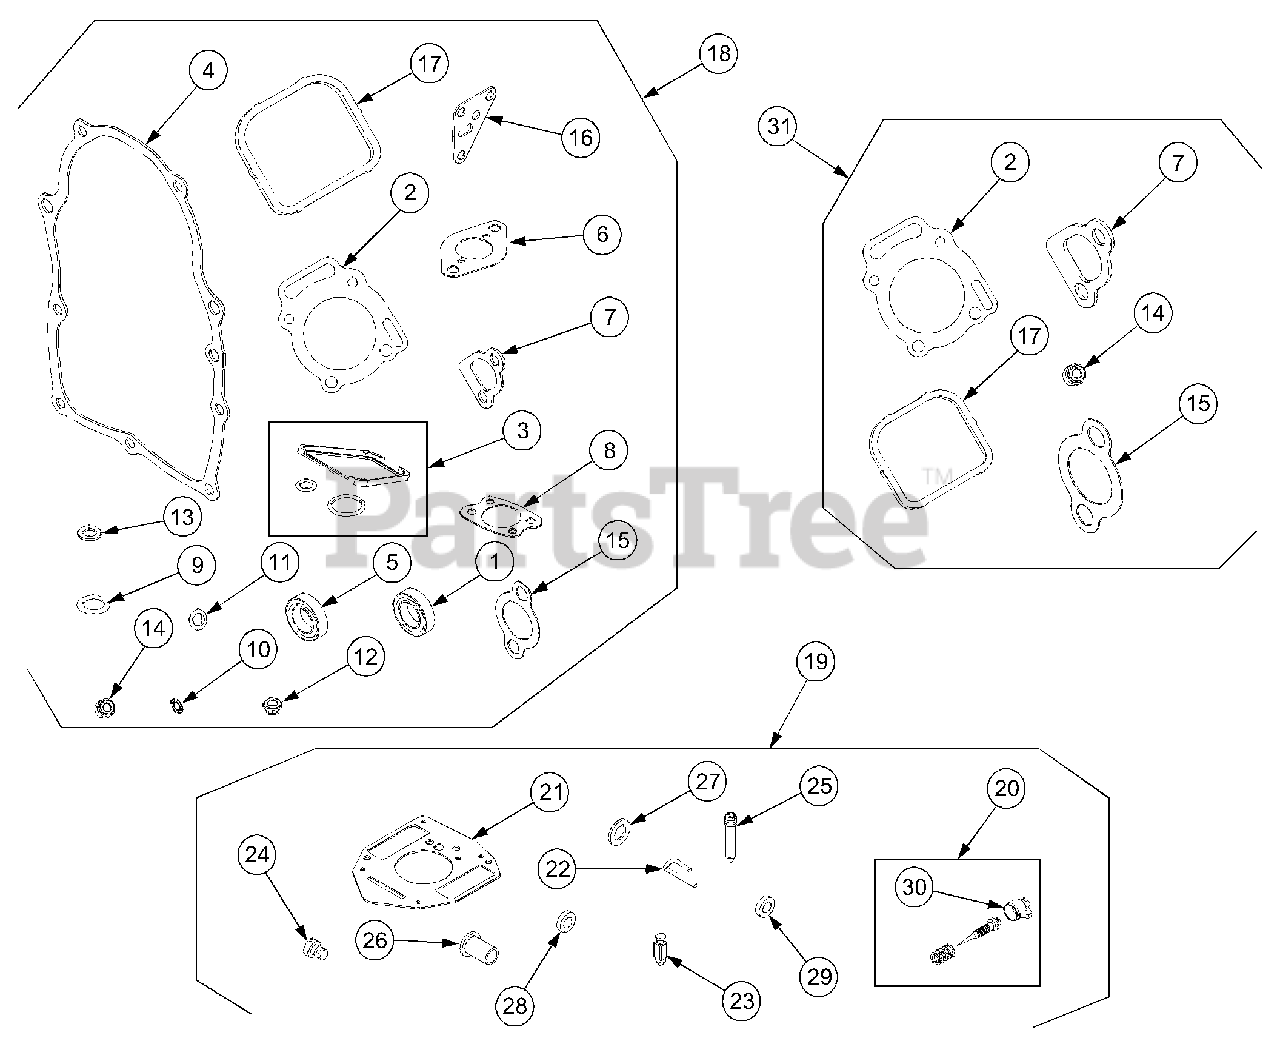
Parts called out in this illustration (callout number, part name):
1	Seal, Oil (Magneto Side)
2	Gasket, Cylinder Head
3	Gasket, Breather
4	Gasket, Crankcase
5	Seal, Oil (PTO Side)
6	Gasket, Intake
7	Gasket, Intake
8	Gasket, Air Cleaner
9	Seal, O-Ring (Oil Pump)
10	Seal, O-Ring (Crankcase Cover)
11	Seal, O-Ring (Oil Pump Screen)
12	Seal, Dipstick Tube
13	Seal, Governor Shaft
14	Seal, Valve
15	Gasket, Exhaust
16	Gasket, Oil Adapter
17	Gasket, Rocker Cover
18	Gasket Set, Engine
19	Kit, Carburetor Overhaul
20	Kit, Idle Mixture
21	Gasket, Carburetor Body
22	Pin, Float Hinge
23	Valve, Float Needle
24	Jet, Main (Standard)
25	Nozzle, Carburetor
26	Bushing, Choke Shaft
27	Washer, Sealing
28	Seal, Choke/Throttle Shaft
29	Seal, Choke/Throttle Shaft
30	Cap, Limiter
31	Gasket Set, Valve
